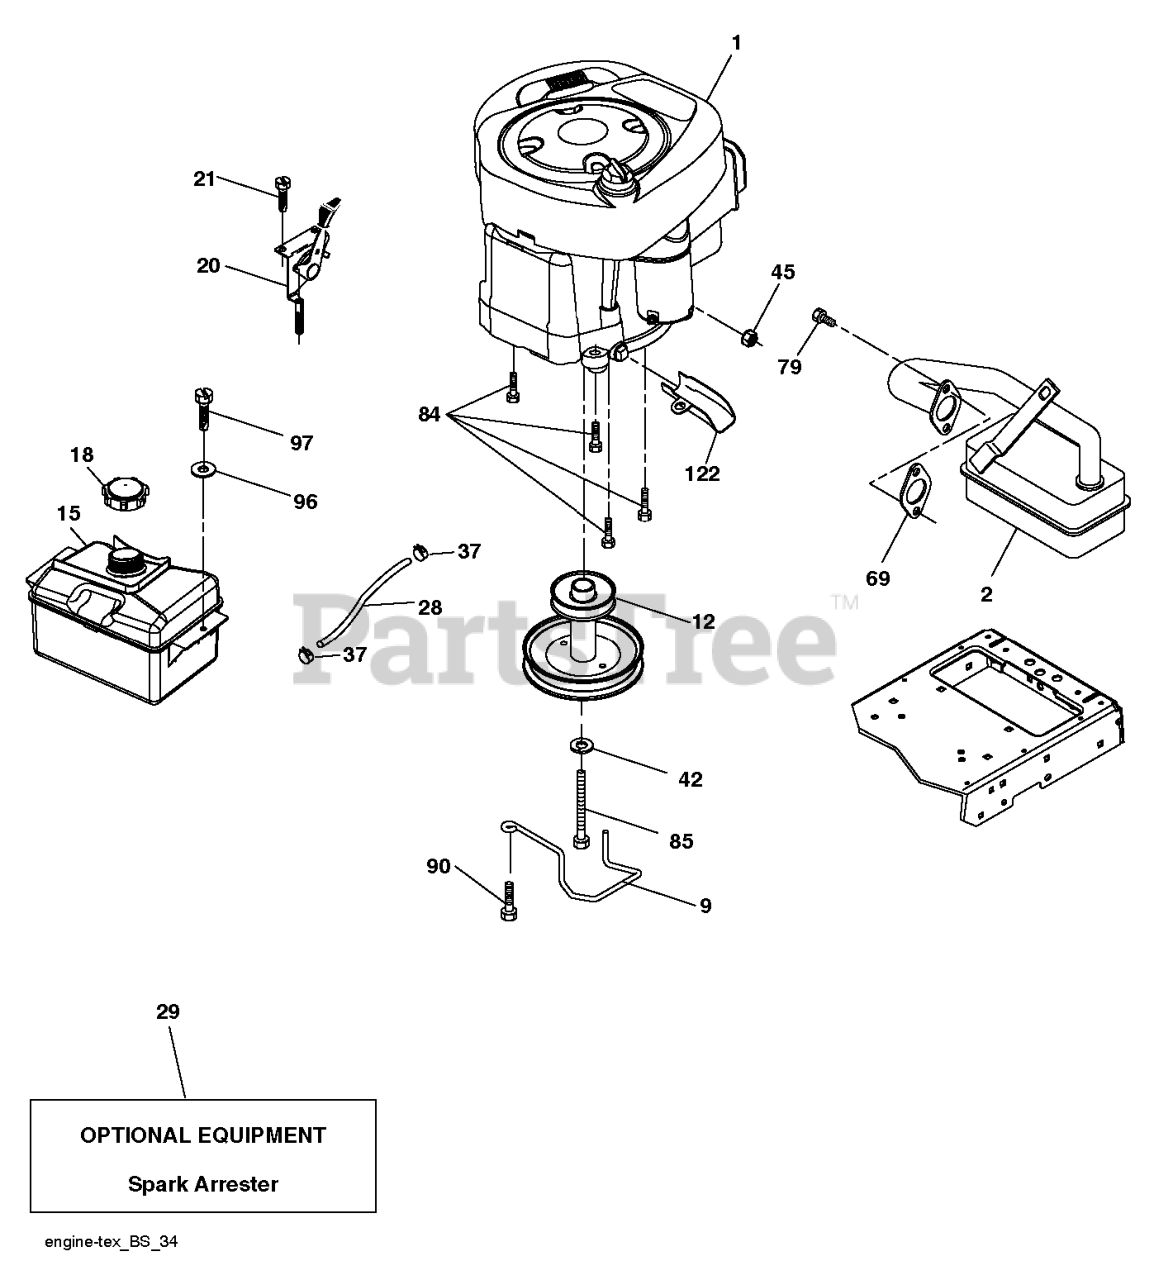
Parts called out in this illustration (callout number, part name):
2	MUFFLER.B&S.MODEL.21.11HP.OHV
9	KEEPER.BELT.ENGINE.3.25 (3 2)
12	PULLEY.ENG.CL.MECH.SLVR.LT/YT
15	RP TANK FUEL FRT 1.5 GAL
18	CAP ASM.FUEL.2.25"FR.
20	CONTROL.TH/CK.C.
21	SCREW.#10 X 0.750.BOS
28	LINE.FUEL.20
29	KIT.SPARK ARRESTOR 794945 B&S
37	HOSE CLAMP
42	LOCKWASHER
45	NUT
69	REPL BY 532 27 22-93
79	SCREW.SOCKET HD.5/16-1
84	SCREW.3/8-16
85	BOLT HEX 7/16-20X4-1/4"
90	SCREW 3/8-16X1
97	SCREW HEXWSHR 1/4-20X3/4
122	EXTENSION DRAIN OIL
